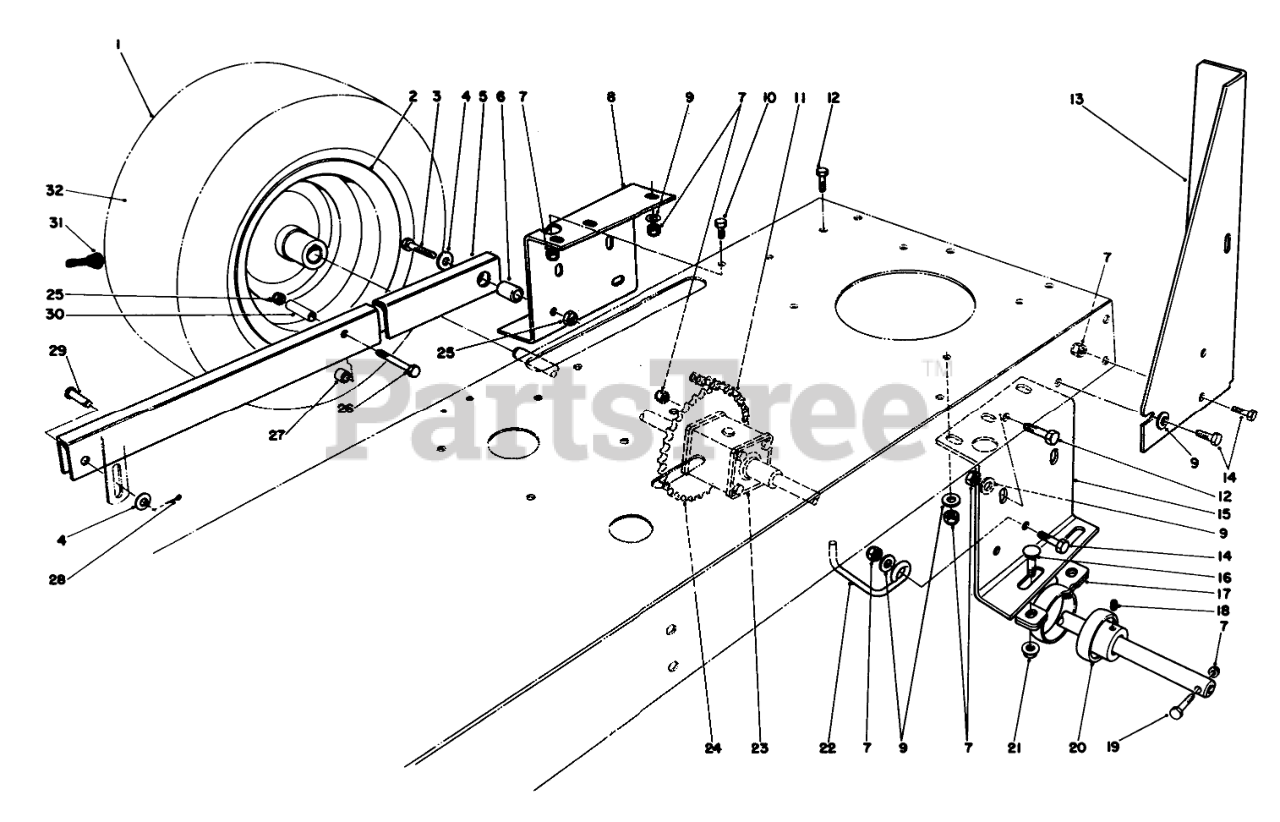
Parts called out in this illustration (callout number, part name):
3	SCREW-HH
4	WASHER-FLAT
5	REAR SUSP ARMR
6	PIN-SUPT ARM
7	NUT-LOCK, NI
8	RH REAR AXLE SUPT R
9	WASHER-PLAIN
10	SCREW-HH
11	ROLLER CHAIN
12	SCREW-HH
13	LH STANDBAR B
14	SCREW-HH
15	LH REAR AXLE SUPT R
16	SCREW-CARR
17	RTNR-PILLOW BLK
18	SCREW-SET, HSH
19	SCREW-HH
20	Bearing-Ball (Incl. Ref. #18)
21	NUT-HF
22	BELT GUIDE
23	DIFFERENTIAL
24	42T DIFF SPROCKET
25	NUT-LOCK, CONE
26	SCREW-HH
27	INNER TUBE SPACER
28	PIN-COTTER
29	PIN-CLEVIS
30	OUTER TUBE SPACER
31	STEM-VALVE
32	TUBE-INNER
